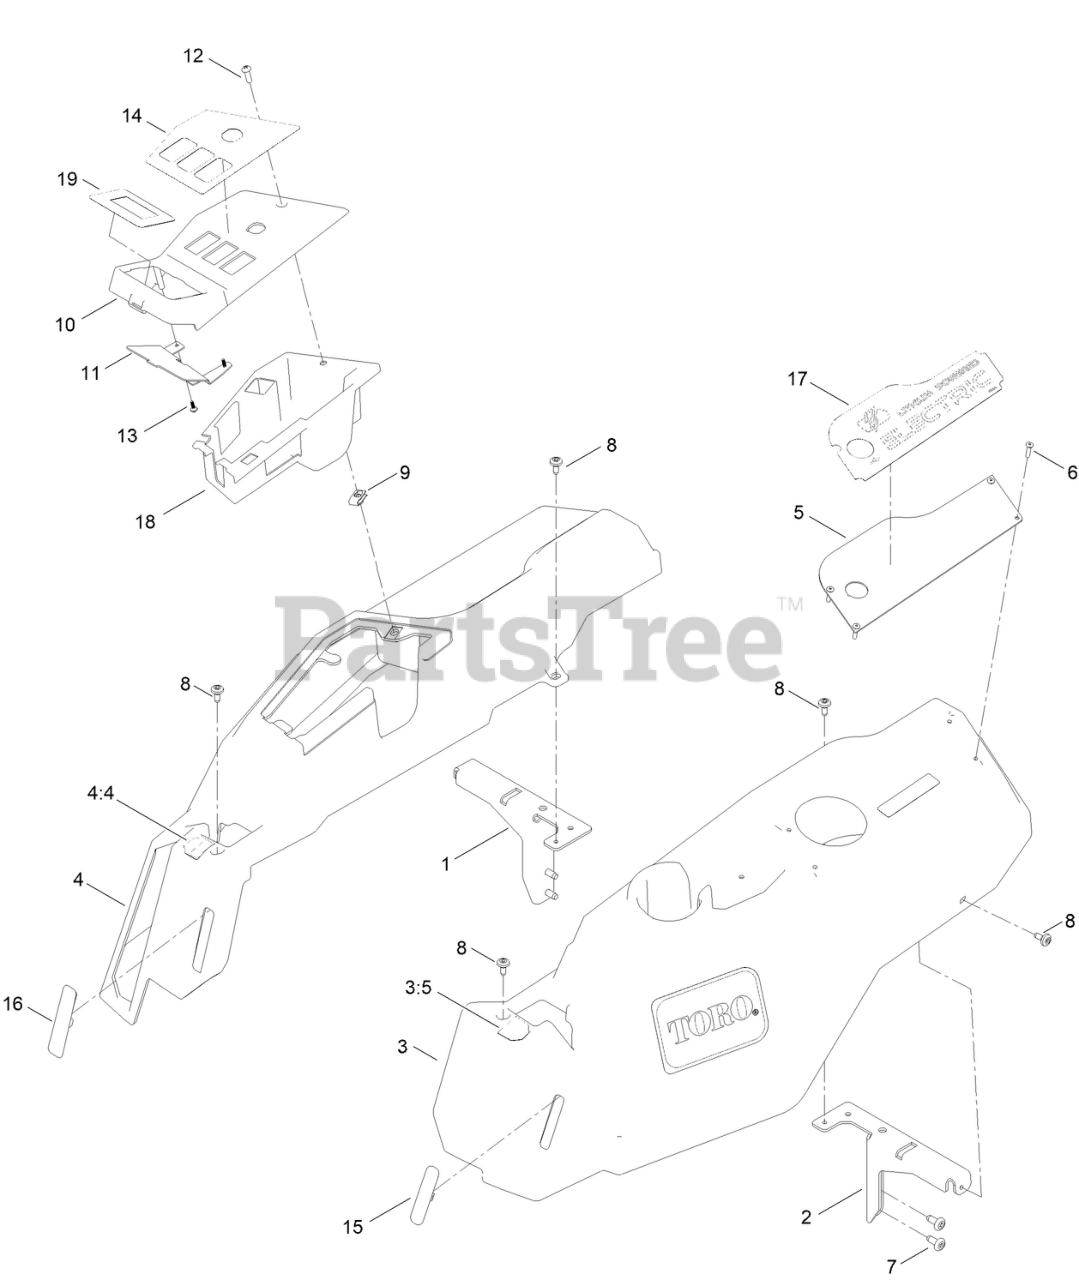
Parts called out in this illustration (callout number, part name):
1	SUPPORT-POD, RH
2	SUPPORT-POD, LH
3	POD-LH
3:5	DECAL - CONTROL LEVER, LH
4	POD-RH
4:4	DECAL - CONTROL LEVER, RH
5	PLATE-COVER, POD
6	RIVET-TRIFOLD
8	SCREW-SHOULDER
10	POD-CONTROL
11	COVER-CONSOLE
12	SCREW-PRH
13	SCREW-PLASTIC,TBFH
14	DECAL-PANEL, CONTROL
15	PLUG-POD, LH
16	PLUG-SC
17	Decal-60V Lithium
18	COVER-SWITCH
19	DECAL-GT DISPLAY
